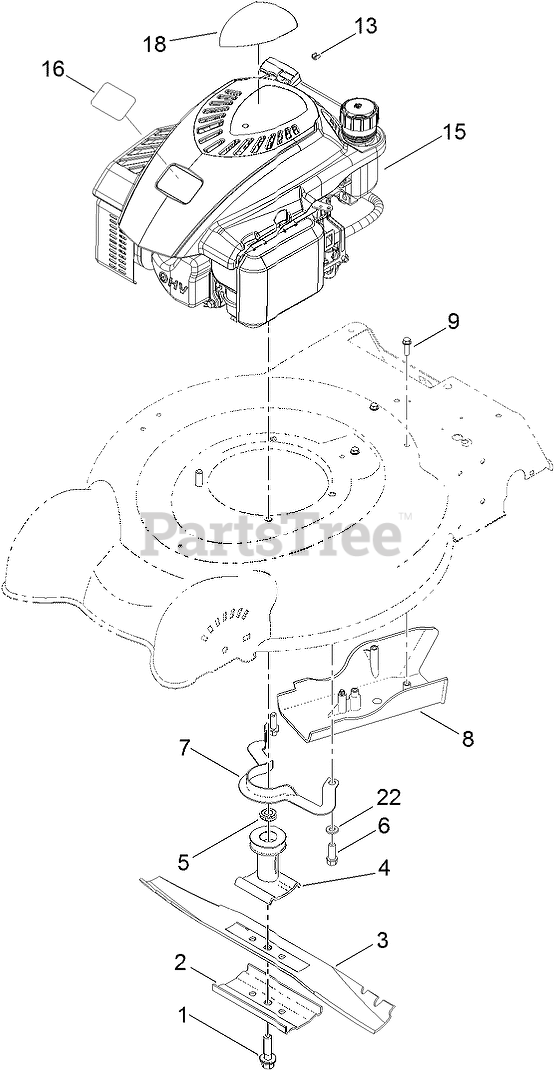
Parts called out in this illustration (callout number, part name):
1	BOLT-BLADE
2	SUPPORT-BLADE
3	BLADE-20 INCH
4	DRIVER-BLADE
5	Spacer-Driver
6	SCREW-TAPTITE
7	Guide-Belt
8	COVER-BELT
9	SCREW-HWH
13	STOP-ROPE
15	ENGINE-1P65FC
16	PLATE-LOGO, TORO
18	DECAL-SHROUD
22	WASHER-FLAT
